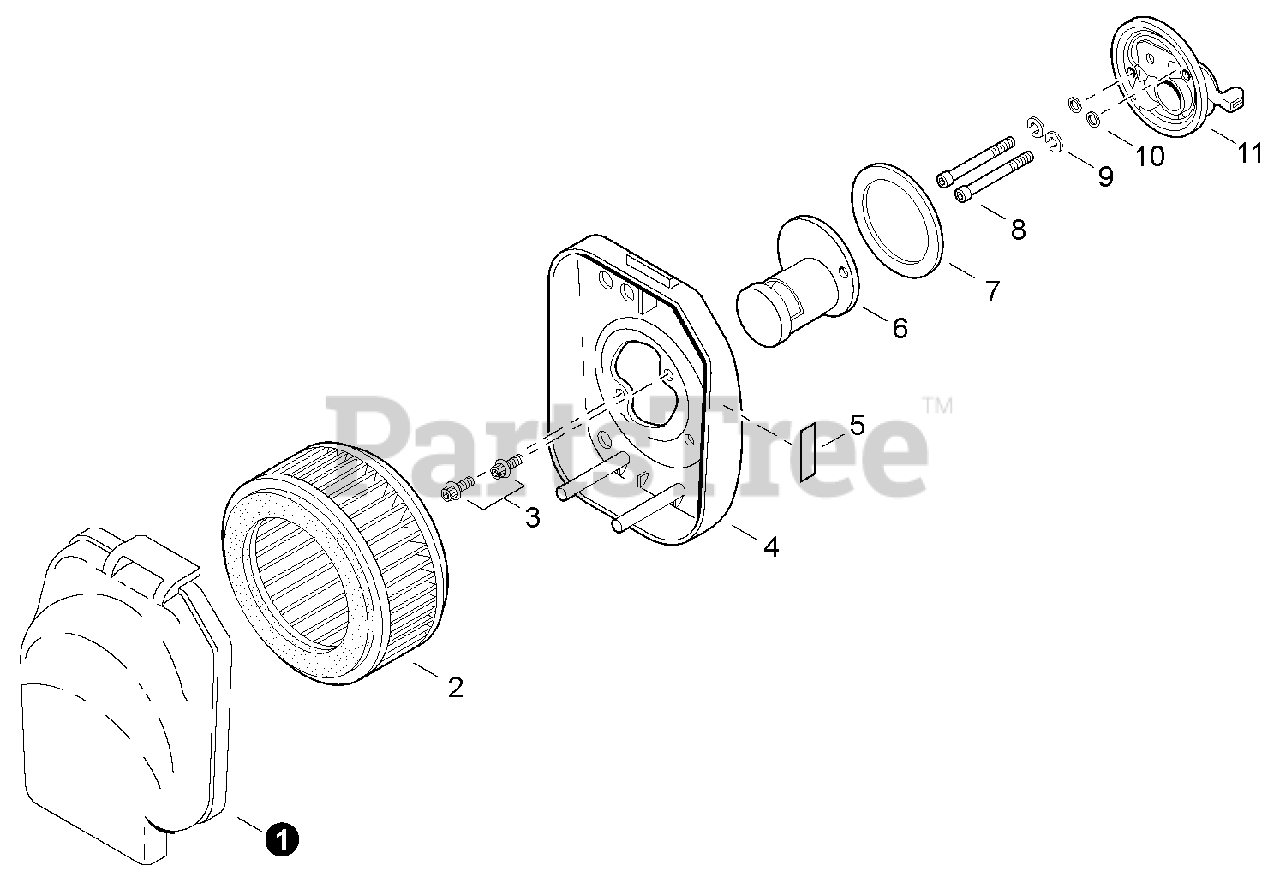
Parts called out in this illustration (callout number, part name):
1	COVER, AIR FILTER
2	FILTER, AIR
3	SCREW - 4X14
4	CASE, AIR FILTER
5	LABEL - CHOKE
6	PIPE - INTAKE
7	GASKET, INTAKE
8	SCREW - 5X60
9	LOCKWASHER - 5
10	WASHER - 5
11	CHOKE ASSY
